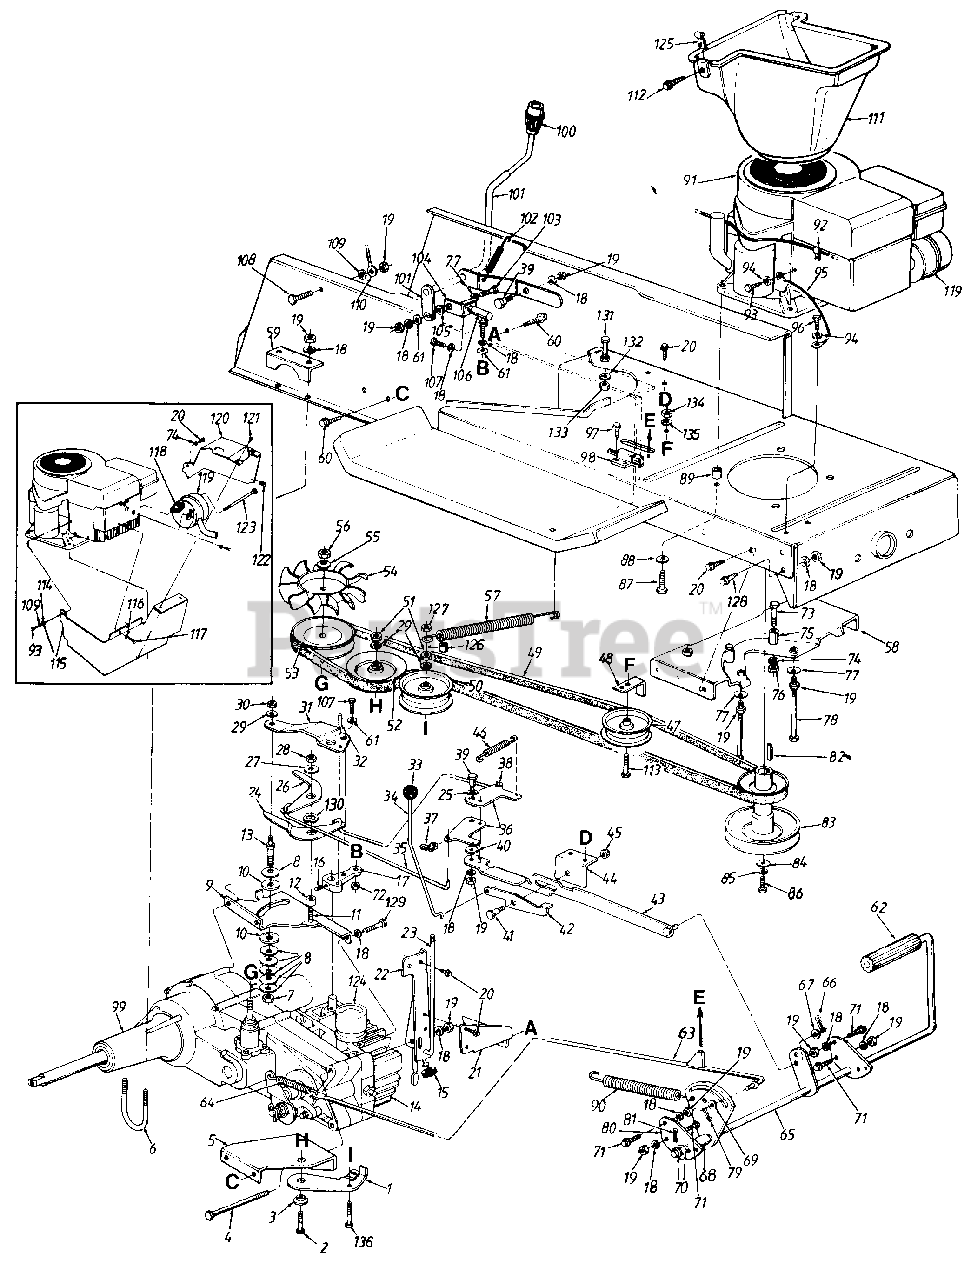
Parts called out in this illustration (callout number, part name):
1	Idler Bracket
2	Hex Bolt 3/8-16 x 2.0" Lg.
3	Shld. Spacer.625" I.D.
4	Hex Bolt 5/16-18 x 4.5" Lg. (Grade 5)
5	Idler Plate
6	U-Bolt 5/16-18 x 1.75" Lg.
7	Hex L-Nut 3/8-24 Thd.
8	Bell-Wash. .40" I.D. x 1.13"
9	Mounting Bracket
10	Friction Washer
11	Rib Neck Bolt 5/16-24 x .84" Lg.
12	Spacer
14	Hydrostatic Pump
15	Rubber Washer .33" I.D.
16	Set Screw
17	Pintle Shift Lever
18	L-Wash. 5/16" I.D.
19	Hex Nut 5/16-18 Thd.
20	Hex Wash. Hd. TT-Tap Scr. 1/4-20 x .5" Lg.
21	Reinforcement Plate
22	Transmission Torque Brkt.
23	Release Valve Rod
24	Reverse Arm
25	Spring Washer .625" I.D.
26	Forward Arm
27	Fl-Wash. .344" I.D. x 1.0"
28	Hex Cent. L-Nut 5/16-24 Thd.
29	L-Wash. 3/8" I.D.
30	Hex Nut 3/8-24 Thd.
31	Pintle Arm Ext. Plate
32	Roll Pin 114" Dia. x .75" Lg.
33	Ball Knob
34	Lock-Up Rod
35	Connection Rod
36	Balancer Bracket
37	Rod End Clevis Clips R.H.
38	Rod End Clevis Clips L.H.
39	Shld. Bolt .437" Dia. x .268"
40	Fl-Wash. .344" I.D. x 1.12"
41	Shld. Bolt .437" Dia. x .35"
42	Lock-Up Bracket
43	Neutral Return Brkt. Ass'y.
44	Bracket
45	Hex Cent. L-Nut 5/16-18 Thd.
46	Ext. Spring 2.5" Lg.
47	Idler Pulley 3.06" O.D.
50	Flat Idler
51	Hex Nut 3/8-16 Thd.
52	Idler Pulley 4.0" O.D.
53	Transmission Pulley
54	Hydro Fan
55	Bell-Wash. .56" I.D. x 1.125"
56	Hex Jam Nut 9/16-18 Thd.
57	Extension Spring
58	Belt Guard Brkt. Ass'y.
59	Bracket
60	Hex Wash. Hd. B-Tap Scr. 5/16-18 x .5" Lg.
61	Flat Tooth Washer 5/16" I.D.
62	Foot Pad
63	Brake Rod Ass'y.
64	Ext. Spring 3.67" Lg.
65	Clutch Brake Pedal Ass'y.
66	Intern. Cotter Pin 5/16" Dia.
67	Fl-Wash. .385" I.D. x .62"
68	Spacer.63" I.D.
69	Fl-Wash. .385" I.D. x .62"
70	Fl-Wash. .635" I.D. x 1.0"
71	Hex Wash. TT-Tap Scr. 5/16-18 x 7/8" Lg.
72	Hex Nut 5/16-24 Thd.
73	Hex Flange Bolt 1/4-20 x 1.5" Lg.
74	L-Wash. 1/4" I.D.
75	Spacer
76	Hex Nut 1/4-20 Thd.
77	Bell-Wash. .345" I.D. x .88"
78	Hex Bolt 5/16-18 x 4.0" Lg.
79	Cotter 3/32" Dia. x .75" Lg.
80	Pedal Brkt.
81	Cotter Pin 3/32" Dia. x 1.0" Lg.
82	Sq.-Key 1/4" x 2.0"
83	Engine Pulley
84	Fl-Wash. 7/16" I.D. x 1.25"
85	L-Wash. 7/16" I.D. (H.D.)
86	Hex Bolt 7/16-20 x 1.5" Lg.
87	Hex Wash. Hd. TT-Tap Scr. 3/8-16 x 1.5" Lg.
88	Fl-Wash. .406" I.D. x 1.25"
89	Spacer .38" I.D. x 1.25" O.D.
90	Extension Spring 6.11" Lg.
91	Engine
92	Speed Clip
93	Truss Mach. Scr. 5/16-18 x .75" Lg.
94	External L-Wash. 5/16" I.D.
95	Electric Ground Wire
96	Hex Wash. AB-Tap Scr. 5/16 x .75"
97	Hex Wash. Hd. B-Tap Scr. #10 x 3/8" Lg.
98	Safety Switch (Clutch)
99	Transaxle
100	Shift Knob
101	Speed Selector Lever Ass'y.
102	Ext. Spring 2.75" Lg.
103	Hex Bolt 5/16-18 x 1.25" Lg.
104	Connection Brkt.
105	Shoulder Nut
106	Ball Joint 5/16-24 Thd.
107	Hex Bolt 5/16-24 x .75" Lg.
108	Hex Bolt 5/16-18 x .75" Lg.
109	External L-Wash. 5/16" I.D.
110	Ground Wire 11.5" Lg.
111	Air Duct
112	Truss Mach. Scr. #10-24 x 5" Lg.
113	Hex Bolt 3/8-24 x 1.75" Lg.
114	Ground Wire 7.25" Lg.
115	Muffler Heat Shield Front
116	L-Wash. .265" I.D.
117	Hex Bolt 1/4-20 x 3/8" Lg.
118	Gasket
119	Muffler
120	Muffler Heat Shield L.H.
121	Hex Wash. Tap Scr. #10 x 5'/ Lg.
122	Speed Nut #10-24 Thd.
123	Shld. Bnlt 7/16" Dia. x 3-5/8"
124	Reservoir
125	Speed Nut #10-24 Thd.
126	Spacer .375" I.D. x .503"
127	Hex Jam Nut 3/8-16 Thd.
128	Hex Wash. TT-Tap Scr. 5/16-18 x .62"
129	Hex Bolt 5/16-18 x 43/4" Lg.
130	Spring Washer .625" I.D.
131	Hex Bolt 1/4-20 x 1.25" Lg.
132	L-Wash. 1/4" I.D.
133	Hex Nut 1/4-20 Thd.
134	Hex L-Nut 3/8-24 Thd.
135	Fl-Wash. .385" I.D. x .87"
136	Hex Bolt 3/8-16 x 2.5" Lg.
